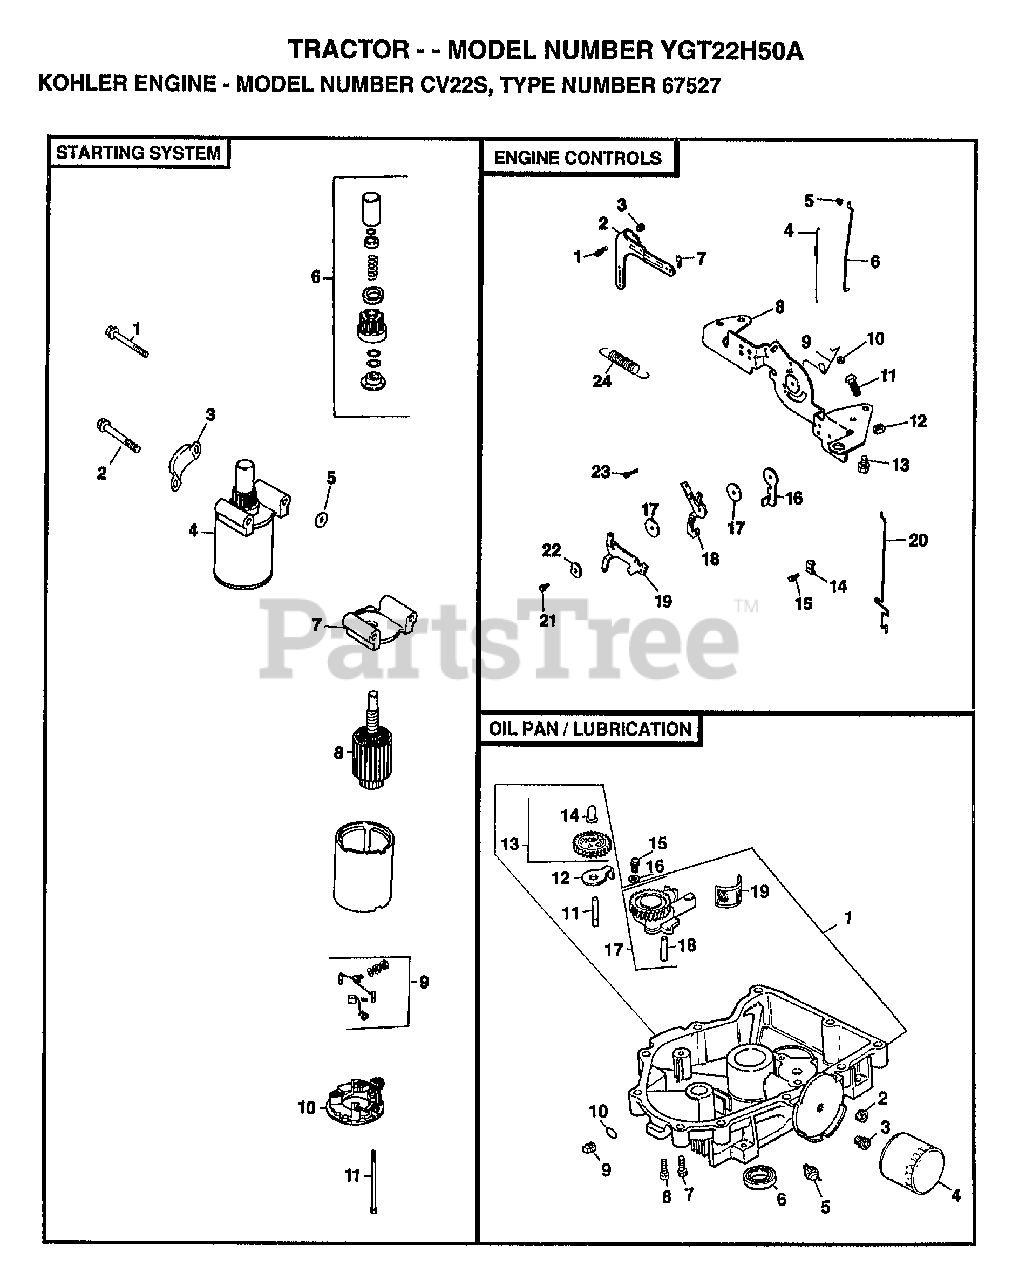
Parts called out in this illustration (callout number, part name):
1	OIL PAN ASSEMBLY
1	SCREW, GOVERNOR ARM
2	PLUG
2	LEVER
3	COVER
3	NIPPLE, OIL FILTER
3	NUT
4	STARTER
4	FILTER, OIL
4	SPRING
5	WASHER
5	OIL PRESSURE SWITCH
5	BUSHING
6	KIT, DRIVE END
6	SEAL, OIL
6	LINKAGE
7	CAP
7	SCREW
7	BUSHING
8	ARMATURE
8	SCREW
8	BRACKET
9	KIT, BRUSH AND SPRING
9	PLUG
9	SPRING
10	CAP
10	O-RING
10	LOCKNUT
11	BOLT
11	SHAFT
11	SCREW
12	TAB
12	NUT
13	KIT, GOVERNOR GEAR WITH PIN
13	SCREW
14	PIN
14	CLAMP, CABLE
15	SCREW
16	WASHER
16	LEVER
17	OIL PUMP ASSEMBLY
17	WASHER
18	TUBE
18	LEVER
19	SCREEN
19	LEVER
20	LINKAGE
22	WASHER
23	SCREW
24	SPRING
